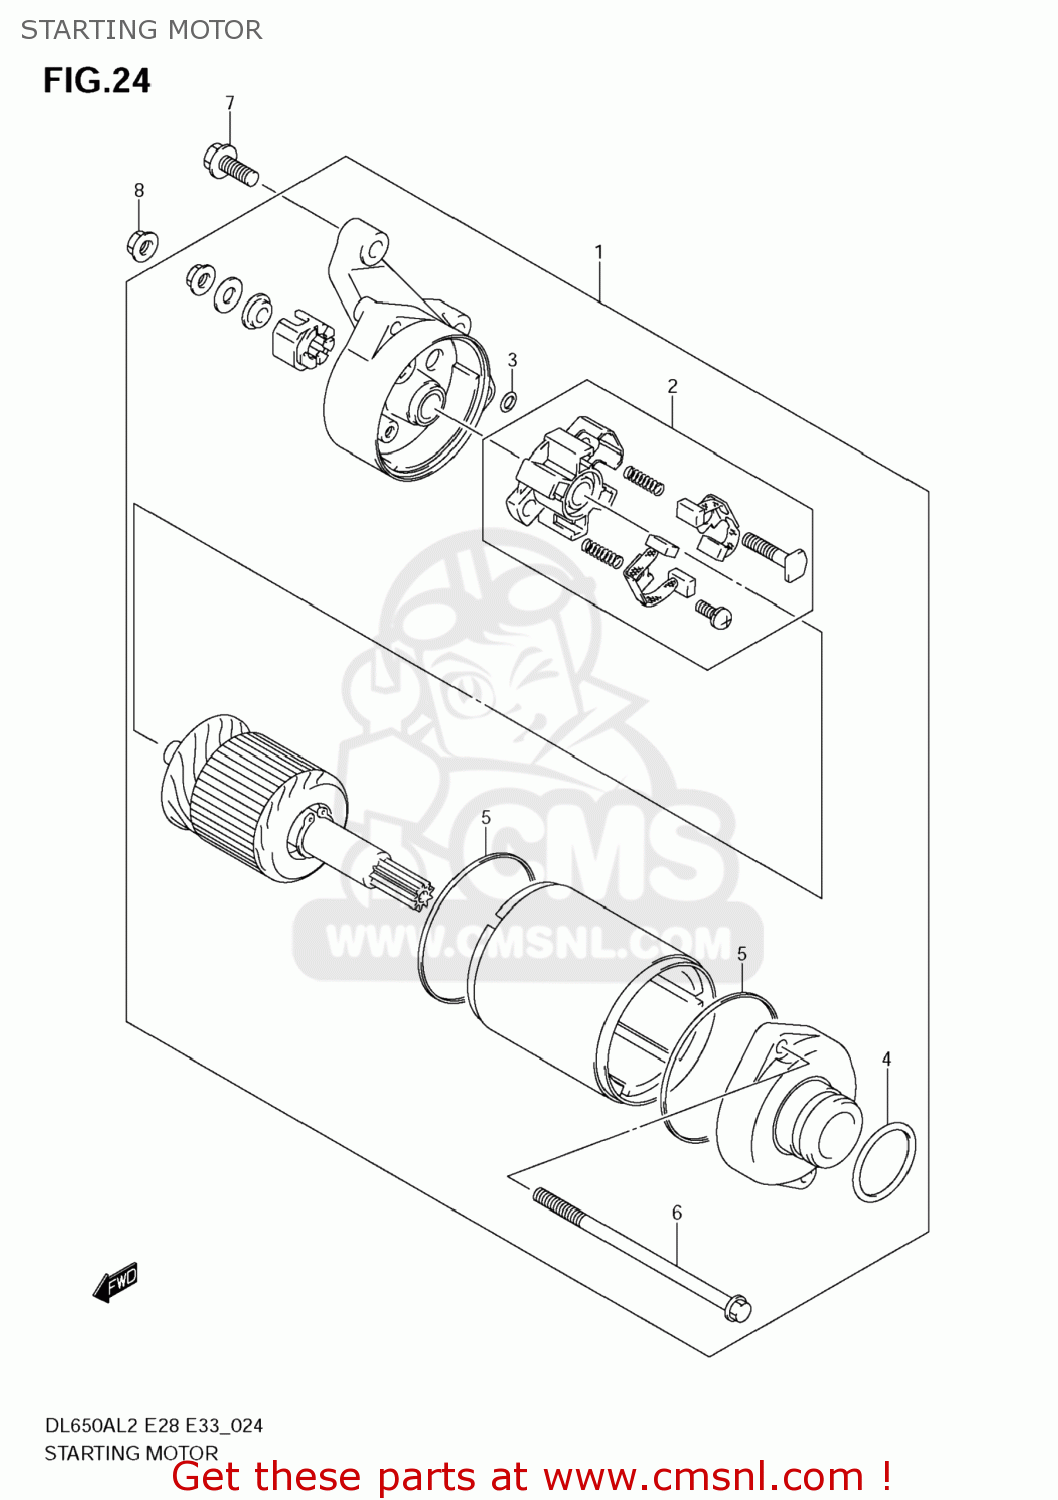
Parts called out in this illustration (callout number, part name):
1	MOTOR ASSY,STARTING
2	BRUSH HOLDER SET
3	O RING
4	O RING
5	SQUARE RING
6	SET,BOLT
7	BOLT(6X25)
8	NUT
